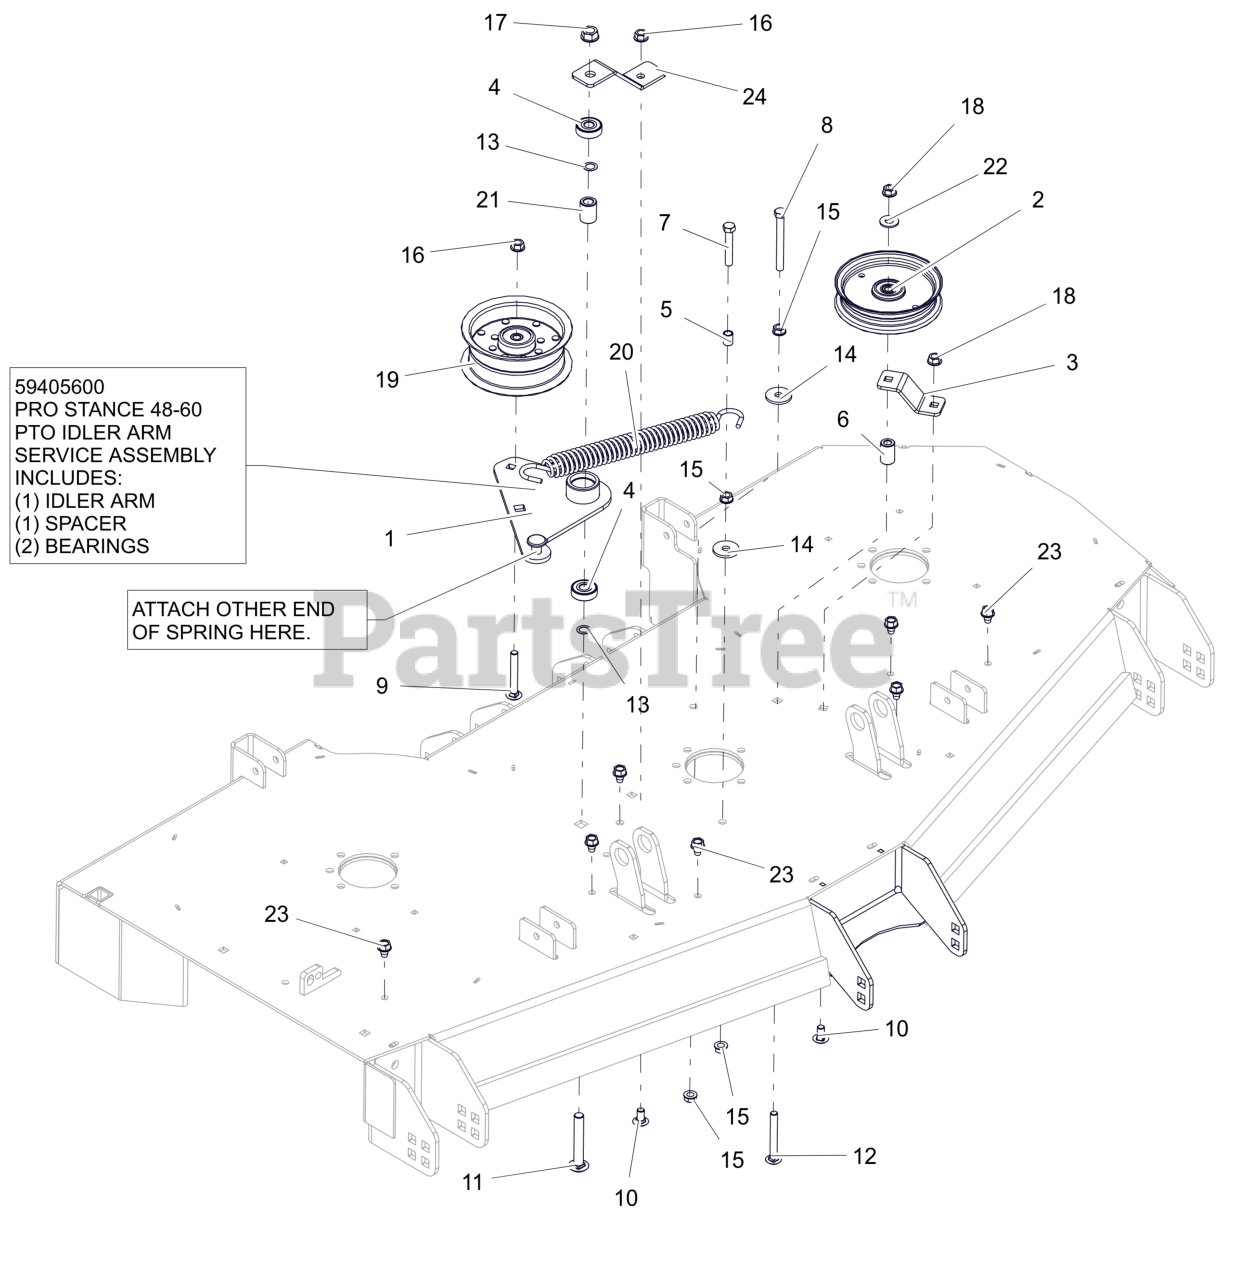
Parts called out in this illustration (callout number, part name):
1	WLDMT, PTO IDLER ARM
1	PTO IDLER ASSEMBLY
2	IDLER- FLAT - 5.00" X .75"
3	PTO FIXED IDLER MTG BRKT -RED
4	BRG-BALL .500X1.38X.437
5	SPCR, SLV .385X.500X.652
6	BUSHING, SLV .380X.750X1.190
7	BLT,HEX .38-16X2.25 G5 ZCC
8	BLT, HEX .38-16X3.50 G5 ZCC
9	BLT, RHSN .38-16X2.75 G5 ZCC
10	BTL,RHSSN .375-16 X 0.75 G5 FPB
11	BTL,RHSSN .500-13 X 3.25 G5 ZCC
12	BTL,RHSSN .375-16 X 3 G5 ZCC
13	WASHER, .500X.750X.020 THRUST
14	WSHR,FLT .406X1.375X.135 ZCC
15	NUT, SPNLK-FLG .38-16 G5 ZCC
16	NUT-LK-CTR-FLG .375-16 GF ZCC
17	NUT-LK-CTR-FLG .500-13 GG ZCC
18	NUT-LK-CTR-FLG .375-16 GF ZCC
19	PULLEY, FLAT 5.00X2.36X.375
20	SPRING, EXTENSION
21	SPACER .510 X .867 X 1.1485
22	WSHR,FLT .438X1.00X.083 ZCC
23	SCR,TAP .375-16X.50 HWH TR ZCC
24	BRKT- PROSTANCE PTO IDLER(RED)
